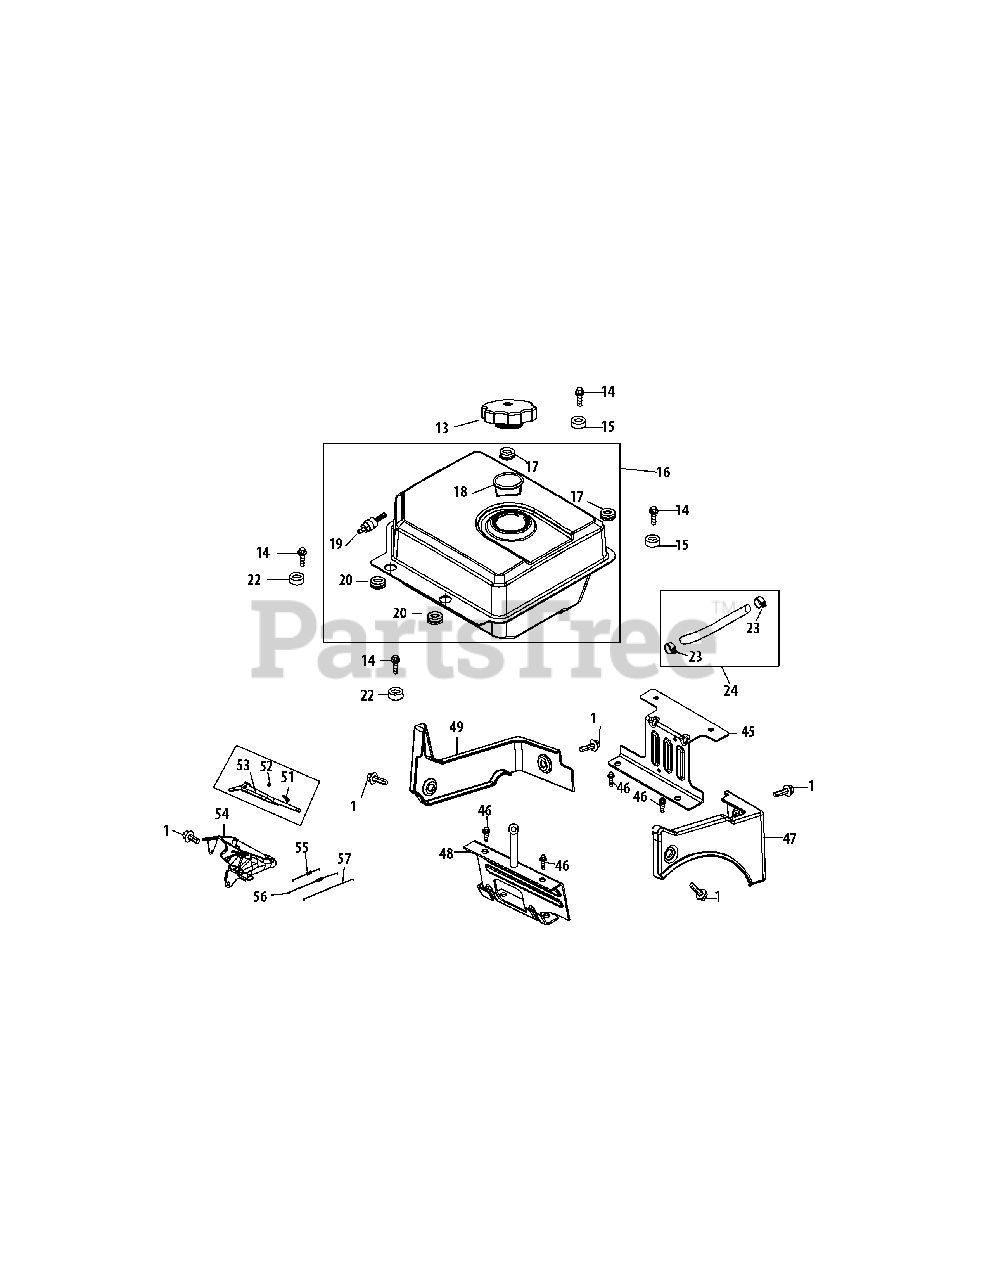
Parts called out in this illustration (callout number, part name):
1	BOLT M6×12
13	FUEL CAP ASSEMBLY
14	BOLT M8×20
15	BUSH, GAS TANK
16	FUEL TANK ASSEMBLY
17	VIBRATION PAD
18	FUEL LEVEL INDICATOR
19	DRAIN PIPE
20	VIBRATION PAD
22	BUSH, GAS TANK
23	FUEL HOSE CLAMP
45	REAR MAINTING BRACKET ASSY.
46	BOLT M8×14
47	RIGHT TRIM PLATE
48	GAS TANK SUPPORT BRACKET
49	LEFT TRIM PLATE
51	GOVERNOR ARM BOLT
53	GOVERNOR ARM
54	THROTTLE BRACKET
55	GOVERNOR SPRING
56	THROTTLE LINKAGE SPRING
57	THROTTLE LINKAGE
